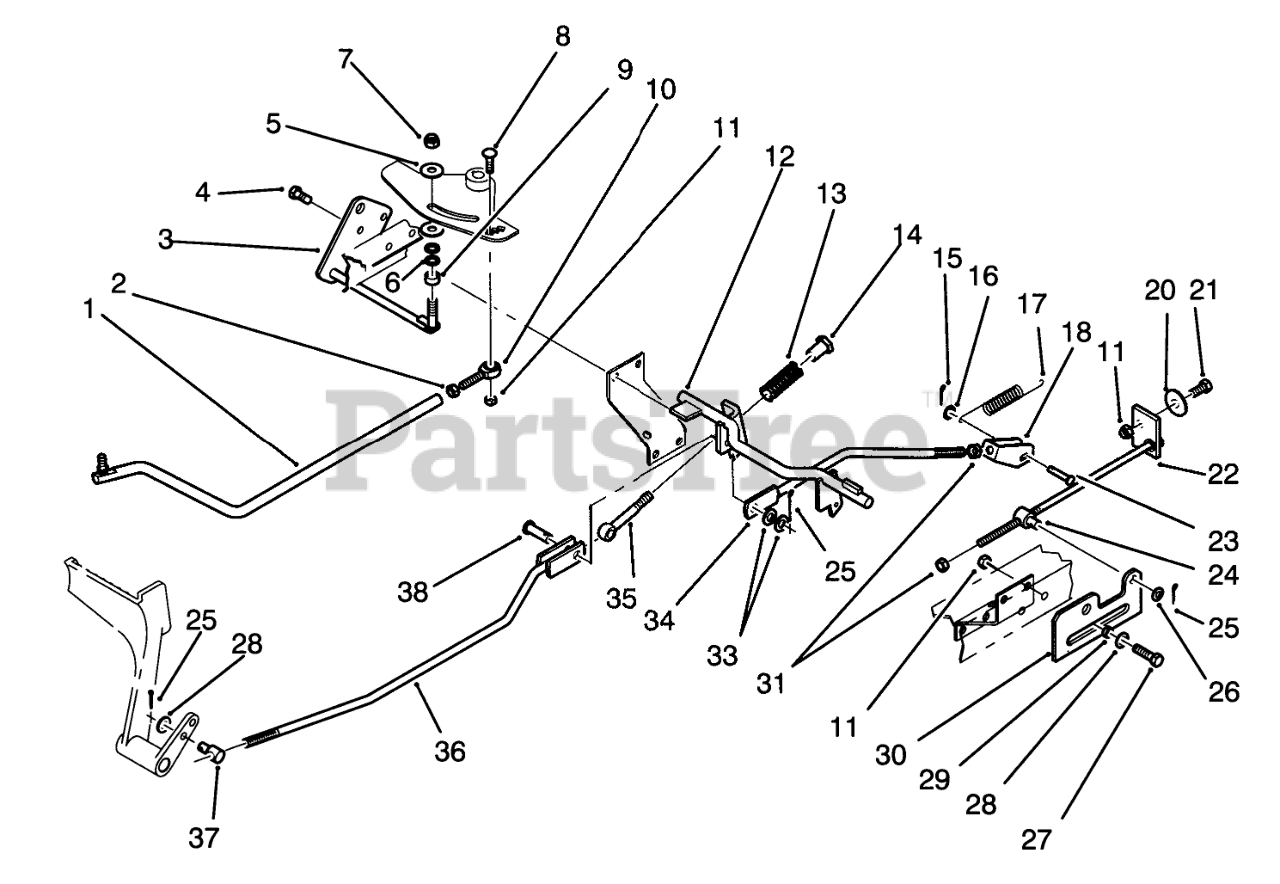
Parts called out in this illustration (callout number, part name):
1	ROD-CONTROL R
2	Nut
3	WLDMT-ROD R
4	Screw
5	FRICTION WASHER
6	WASHER-SPRING DISC
7	NUT
8	Bolt-Carriage
9	SPACER
10	BALL-END
11	NUT-LOCK, NI
12	WLDMT-NEUTRAL SHA R
13	SPRING-COMPRESSION
14	NUT-RETAINER
15	PIN-COTTER
16	WASHER-FLAT
17	SPRING-EXTENSION
18	WLDMT-CLEVIS
20	WASHER
21	SCREW-HH
22	WLDMT-BOLT
23	Pin-Clevis
24	TRUNNION
25	PIN-COTTER
26	WASHER-PLAIN
27	SCREW-HH
28	WASHER-PLAIN
29	SPACER
30	PLATE R
31	NUT-JAM
33	Washer
34	WLDMT-ROD
35	EYE-BOLT
36	WLDMT-BRAKE ROD
37	TRUNNION
38	CLEVIS PIN
